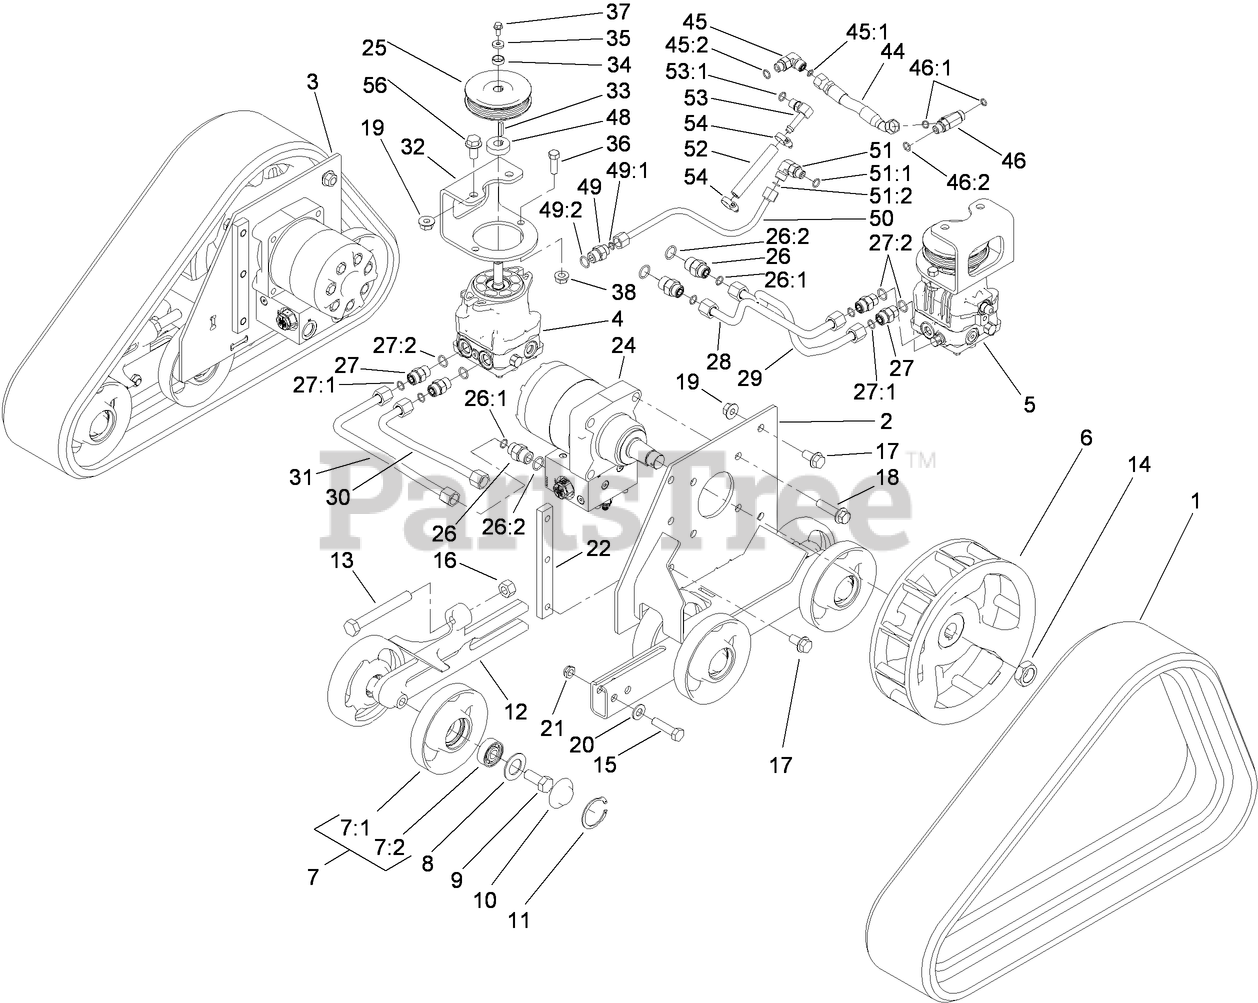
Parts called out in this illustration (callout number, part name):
1	TRACK-RUBBER
2	FRAME-TRACK, LH
3	FRAME-TRACK, RH
4	RH HYD PUMP ASM
5	LH HYD PUMP ASM
6	WHEEL-DRIVE
7	WHEEL-TENSIONER
7:1	WHEEL-TRACK
7:2	BEARING
8	Gasket-Bogie
9	SCREW-HH
10	CAP-WHEEL, BEARING
11	RING-SNAP, INTERNAL
12	TENSIONER-TRACK
13	SCREW-HH, TAP
14	NUT-LOCK
15	SCREW-HH
16	NUT-HEX
17	SCREW-HHF
18	SCREW-HHF
19	NUT-HHF
20	WASHER-FLAT
21	NUT-LOCK, NI
22	BAR-THREAD
24	HYD MOTOR ASM
25	SHEAVE
26	FITTING-STRAIGHT
26:1	O-RING
26:2	O-RING
27	FITTING-STRAIGHT
27:1	O-RING
27:2	O-RING
28	TUBE-HYD
29	TUBE-HYD
30	TUBE-HYD
31	TUBE-HYD
32	BRACKET-MOUNT, PUMP
33	KEY-PUMP
34	BUSHING
35	WASHER
36	SCREW-HH
37	SCREW-HHF
38	NUT-HF
44	HOSE-HYD
45	FITTING-ELBOW, 90 DEG
45:1	O-RING
45:2	O-RING
46	FITTING-TEE
46:1	O-RING
46:2	O-RING
48	SPACER
49	FITTING-STRAIGHT
49:1	O-RING
49:2	O-RING
50	TUBE-HYD
51	FITTING-ELBOW, 90 DEG
51:1	O-RING
51:2	O-RING
53	FITTING-ELBOW, 90
53:1	O-RING
54	CLAMP-HOSE
56	SCREW-HH
